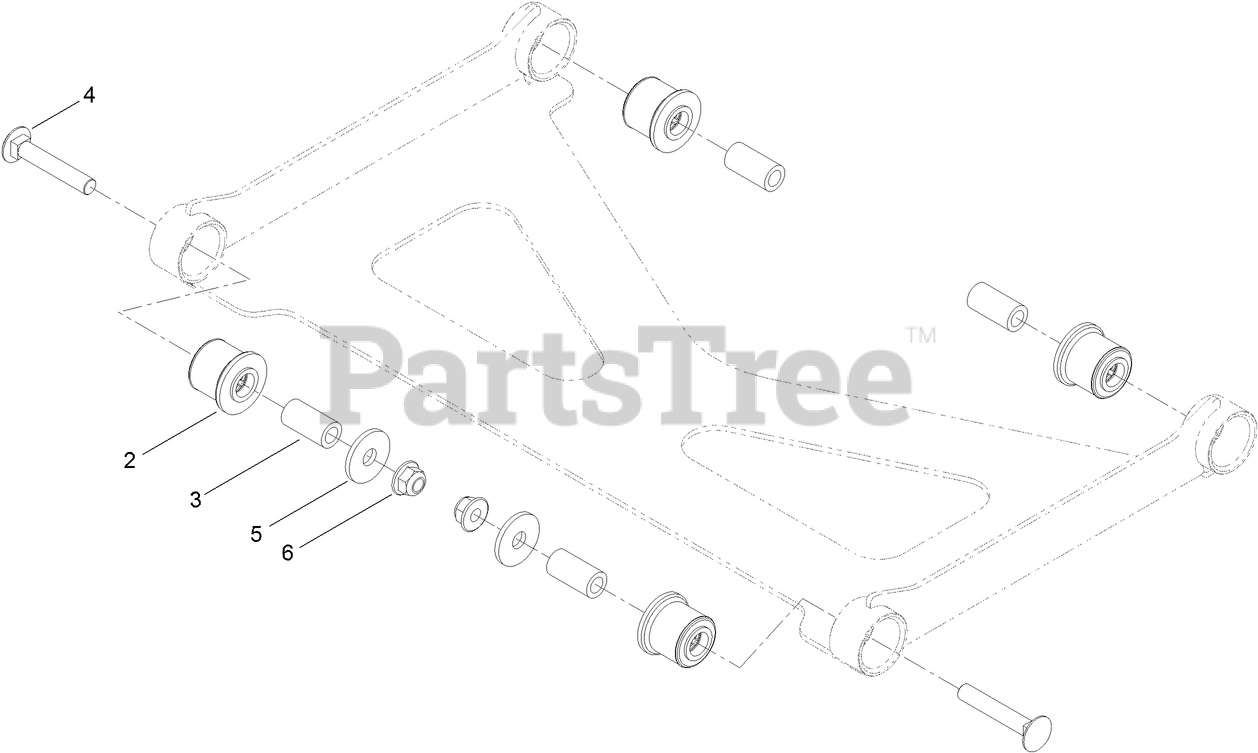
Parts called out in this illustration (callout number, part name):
2	BUSHING-RUBBER, SUSPENSION
3	SPACER
4	SCREW-CARR
5	WASHER
6	NUT-HF, NI
